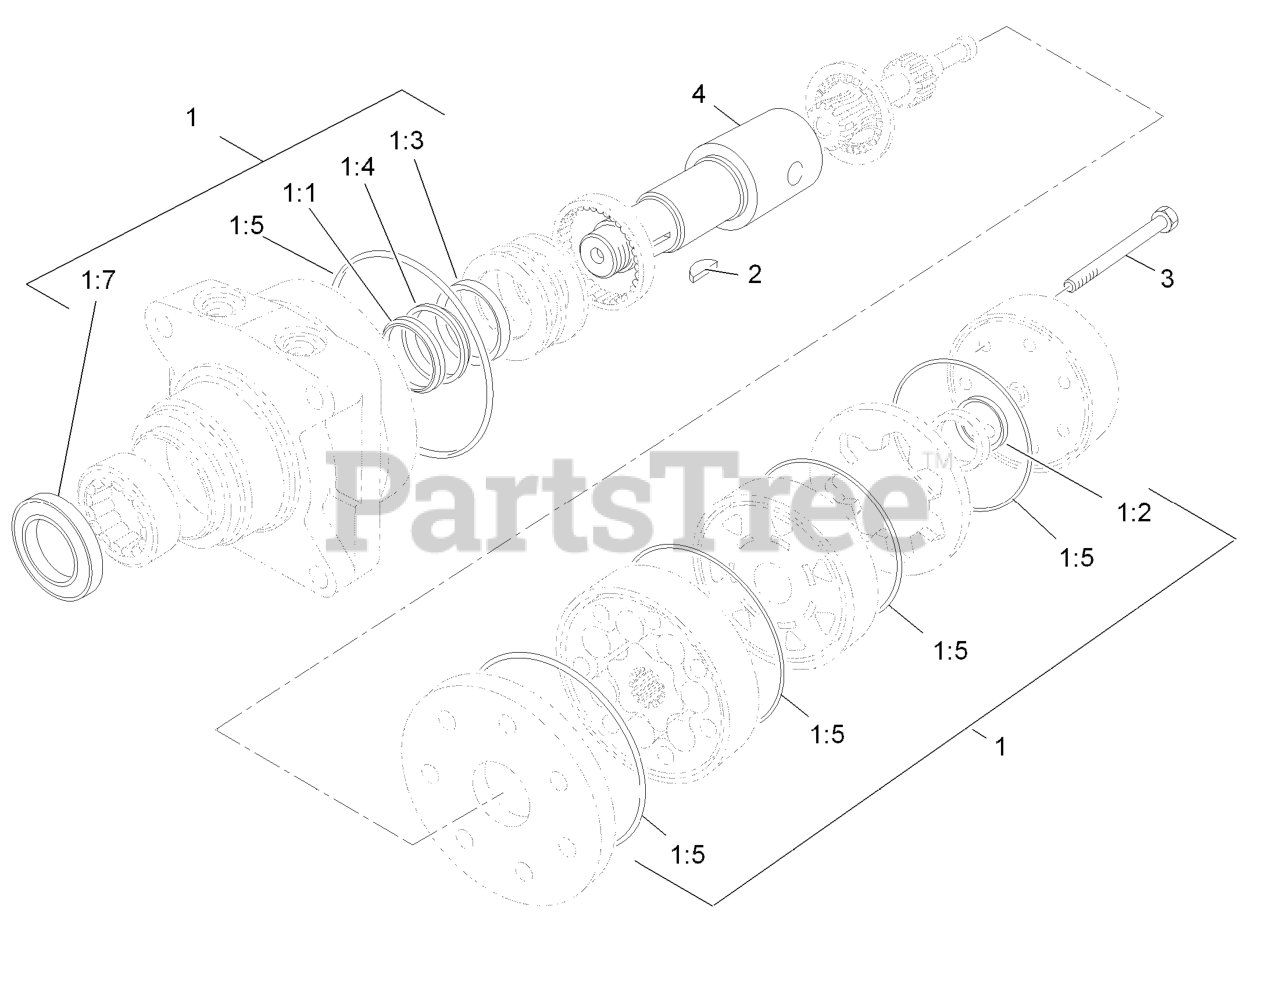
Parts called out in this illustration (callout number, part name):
1	SEAL KIT
1:1	Ring-Back Up
1:2	Seal-Commutator
1:3	Seal-Shaft (Viton)
1:4	Washer-Back Up, Steel
1:5	Ring-Seal (Viton)
1:7	Seal-Dirt And Water
2	KEY-WOODRUFF
3	BOLT-SPECIAL
4	SHAFT-COUPLING
